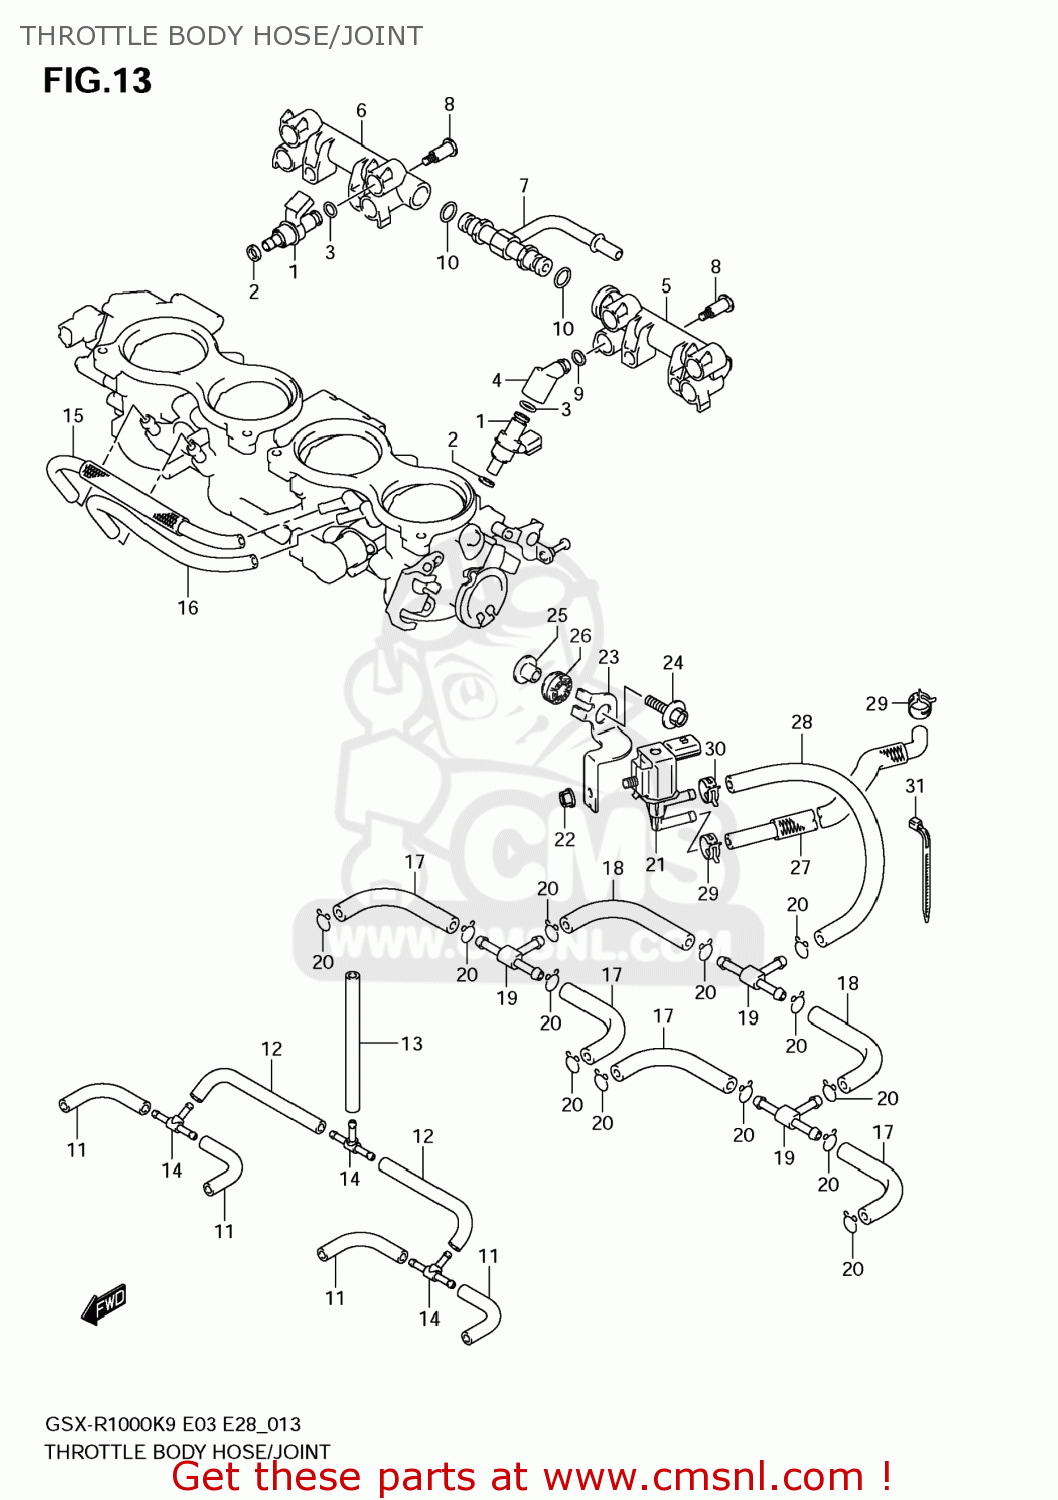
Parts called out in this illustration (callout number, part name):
1	INJECTOR ASSY
2	RING,SEAL
3	O RING
4	PIPE,FUEL
5	PIPE,FUEL
6	PIPE,FUEL
7	JOINT
8	SCREW
9	O RING
10	O RING
11	HOSE
12	HOSE
13	HOSE,RUBBER(L:100)
14	JOINT
15	TUBE
16	TUBE
17	HOSE
18	HOSE
19	JOINT
20	CLIP
21	VALVE,CANISTER PURGE
22	NUT
23	BRACKET,SOLENOID VALVE
24	BOLT(6X30)
25	SPACER(6.5X10X11.6)
26	CUSHION
27	HOSE,PURGE VALVE
28	HOSE
29	CLIP
30	CLIP
31	CLAMP(L:125)
